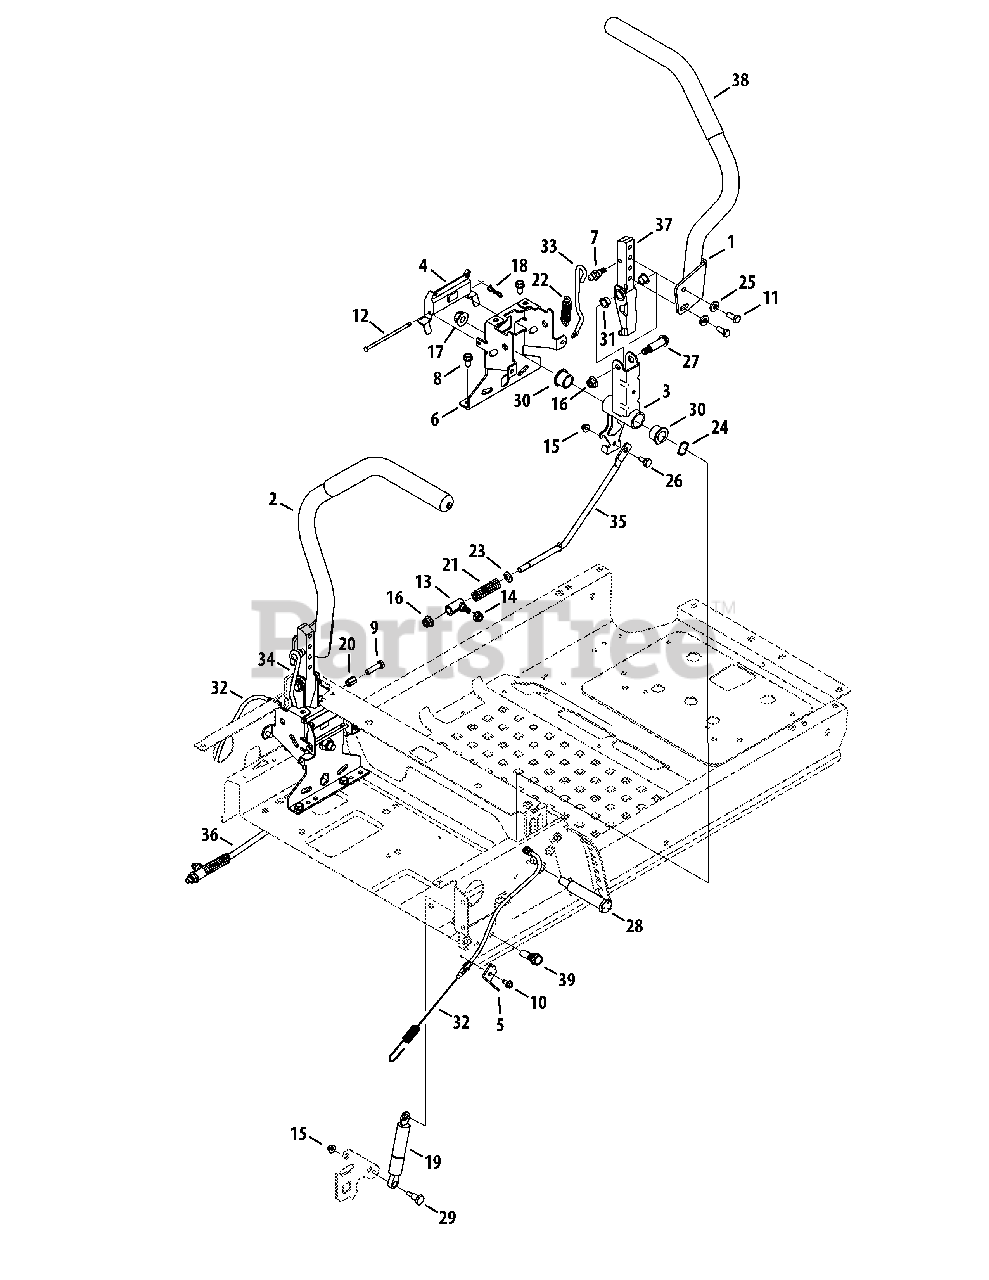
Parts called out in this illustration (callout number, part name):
1	RH Lapbar Lever Assembly
2	LH Labpar Lever Assembly
3	Lapbar Pivot Bracket
4	Brake Lever Actuator
5	Brake Cable Bracket
6	Lapbar Pivot Support Bracket
7	Screw, Shoulder Ball, 5/16-18 x .48
8	Hex Washer Screw, 5/16-18 x .750
9	Hex Cap Screw, 5/16-18 x 1.25
10	Hex Washer Screw, 1/4-20 x .500
11	Hex Head Screw, 5/16-18 x .75 Patch
12	Pin, .188 x 4.1
13	Ferrule, 3/8 ID x .420 Shldr
14	Flange Lock Nut, 5/16-18
15	Flange Lock Nut, 1/4-20
16	Flange Lock Nut, 3/8-16
17	Flange Lock Nut, 1/2-13
18	Bow-Tie Cotter Pin
19	Dampener, .87 OD x 7.06 Lg
20	Nut, 5/16-18
21	Compression Spring, .45 x 3.215
22	Extension Spring, .56 x 2.31 x .105
23	Flat Washer, .385 x .62 x .063
24	Washer, Wave, .785 x 1.0 x .012
25	Flat Washer, .344 x .750 x .120
26	Shoulder Screw, .375 Dia. x .181
27	Shoulder Screw, .498 Dia. x 1.296
28	Shoulder Screw, .75 x 3.25 x 1/2-13
29	Shoulder Screw, .395 Dia. x .56
30	Bearing, .75 x 1.00 x .73
31	Flange Bearing, .500 x .627
32	Park Brake Cable
33	Lapbar Detent Rod, RH
34	Lapbar Detent Rod, LH
35	Hydro Control Rod, RH
36	Hydro Control Rod, LH
37	Lower Arm
38	Lapbar Grip, Short 1.125 x 5.0 Lg
39	Shoulder Screw, .395 Dia. x .83
